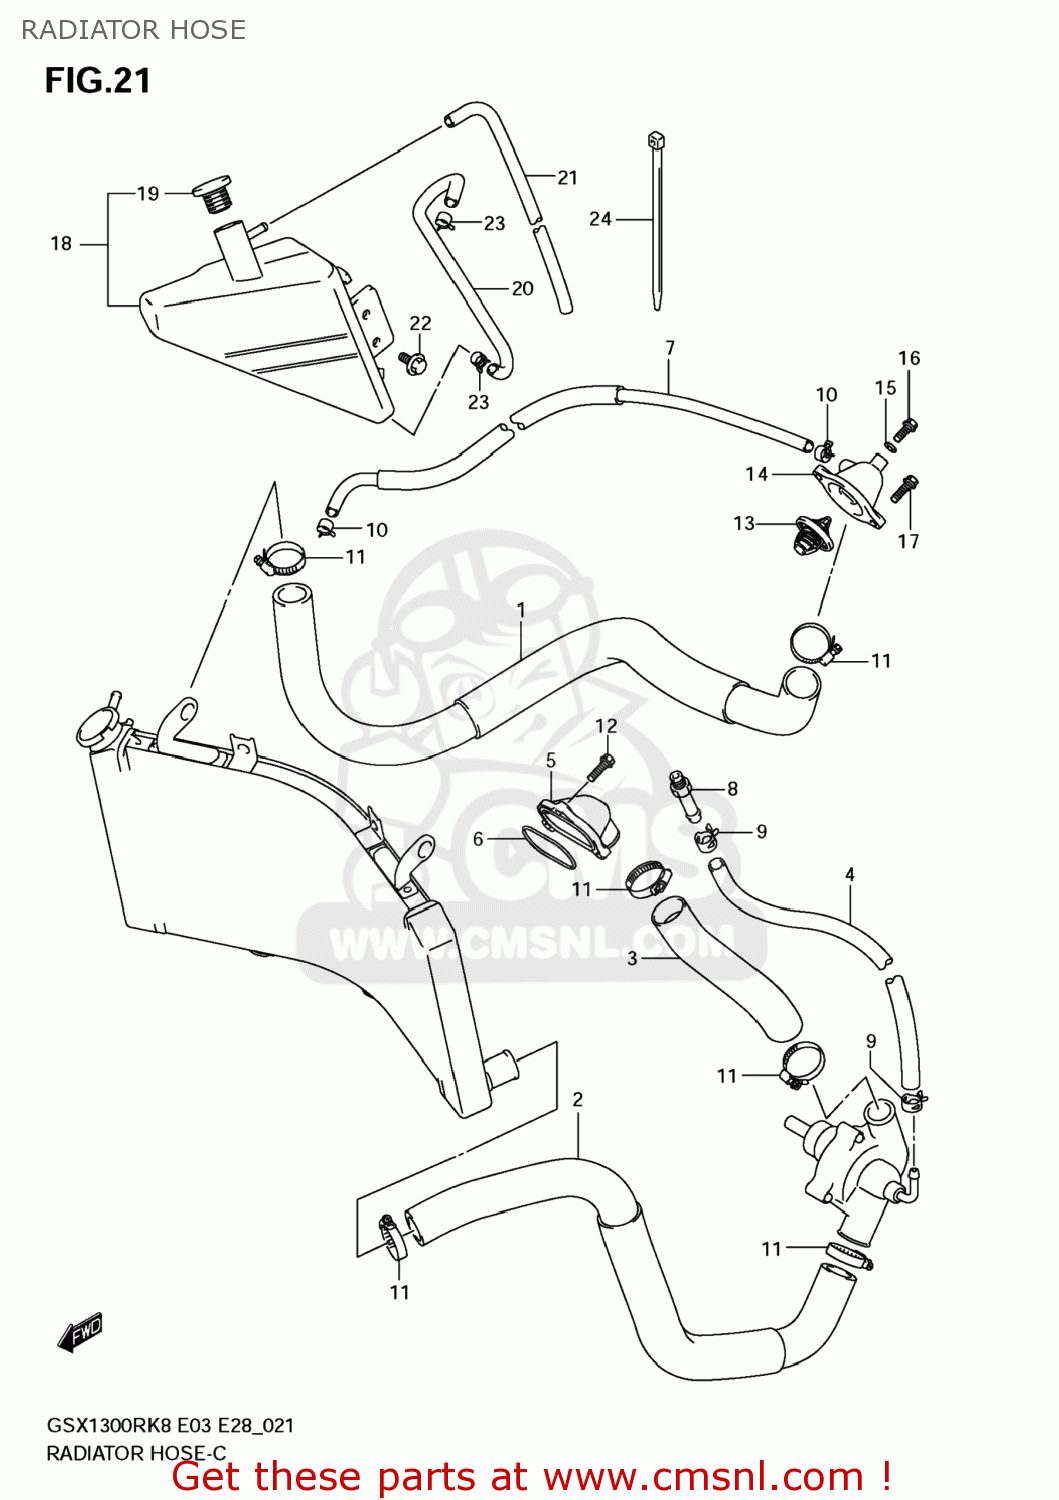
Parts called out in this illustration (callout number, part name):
1	HOSE,RADIATOR INLET
2	HOSE,RADIATOR OUTLET
3	HOSE,CYLINDERL INLET
4	HOSE,WATER BYPASS NO.1
5	CONNECTOR,CYLINDER WATER INLET
6	O RING,CYL WATER CONNECTOR
7	HOSE,WATER AIR BLEED
8	BOLT UNION
9	CLAMP
10	CLIP
11	CLAMP
12	BOLT
13	THERMOSTAT,WATER
14	COVER,THERMOSTAT
15	GASKET(6.4X11.5X0.8) (NAS)
16	UNION BOLT,AIR VENT
17	BOLT
18	TANK ASSY,RESERVOIR
19	CAP,RESERVOIR TANK
20	HOSE,RESERVOIR TANK INLET
21	HOSE,RESERVOIR TANK OVFL
22	BOLT(6X12)
23	CLIP
24	CLAMP(L:145)
